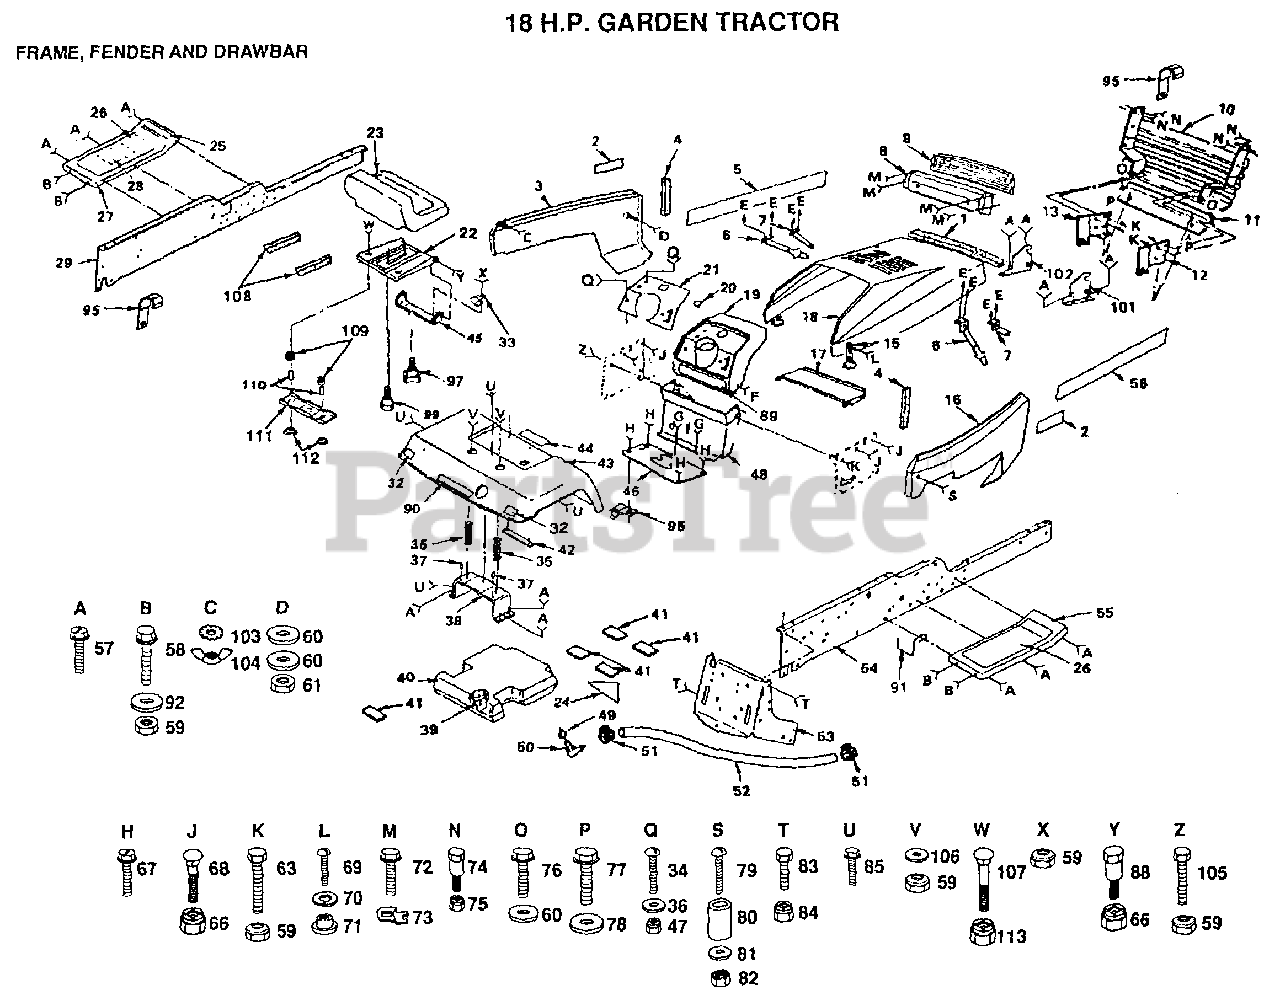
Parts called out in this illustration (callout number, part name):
4	FOAM STRIP T
5	DECAL HOOD LH
9	LENS LT
12	SUPPORT RH YTH
13	SUPPORT LH YTH
15	HOOD LATCH T
20	PLUG-DASH T
25	DECAL T
26	PAD FOOTREST T
27	FOOTREST LH YT
28	DECAL - DRIVE BELT
32	REFLECTOR-TAIL YT
33	CLIP T
34	SCREW
35	SPRING COMPRESSIO
36	WASHER
37	NUT-PUSH YT
41	PAD-SPACER LT
44	DECAL
46	CVR SHAFT GATE
48	DASH ASSEMBLY
49	BUSHING OUTLET T
50	FUEL TANK STEM GT
51	HOSE CLAMP
57	SCREW
60	WASHER PM
63	BOLT
64	WASHER
65	SCREW
68	BOLT
69	SCREW
70	LOCKWASHER
71	WELDNUT
73	"""J"" FASTENER LT"
76	SCREW
77	SCREW
78	WASHER
79	SCREW
80	SPACER LT
81	WASHER
83	BOLT
84	NUT GTV
85	SCREW LT
91	BELT RETAINER GT
92	WASHER
97	"KNOB 1/2"" YT"
101	SUPPORT RH YTH
102	SUPPORT LH YTH
103	LOCKWASHER GT
106	WASHER
107	BOLT
108	STRIP FORM
109	SPRING
110	SPACER SPLIT
111	BRKT SWITCH
112	BUSHING
114	NUT
